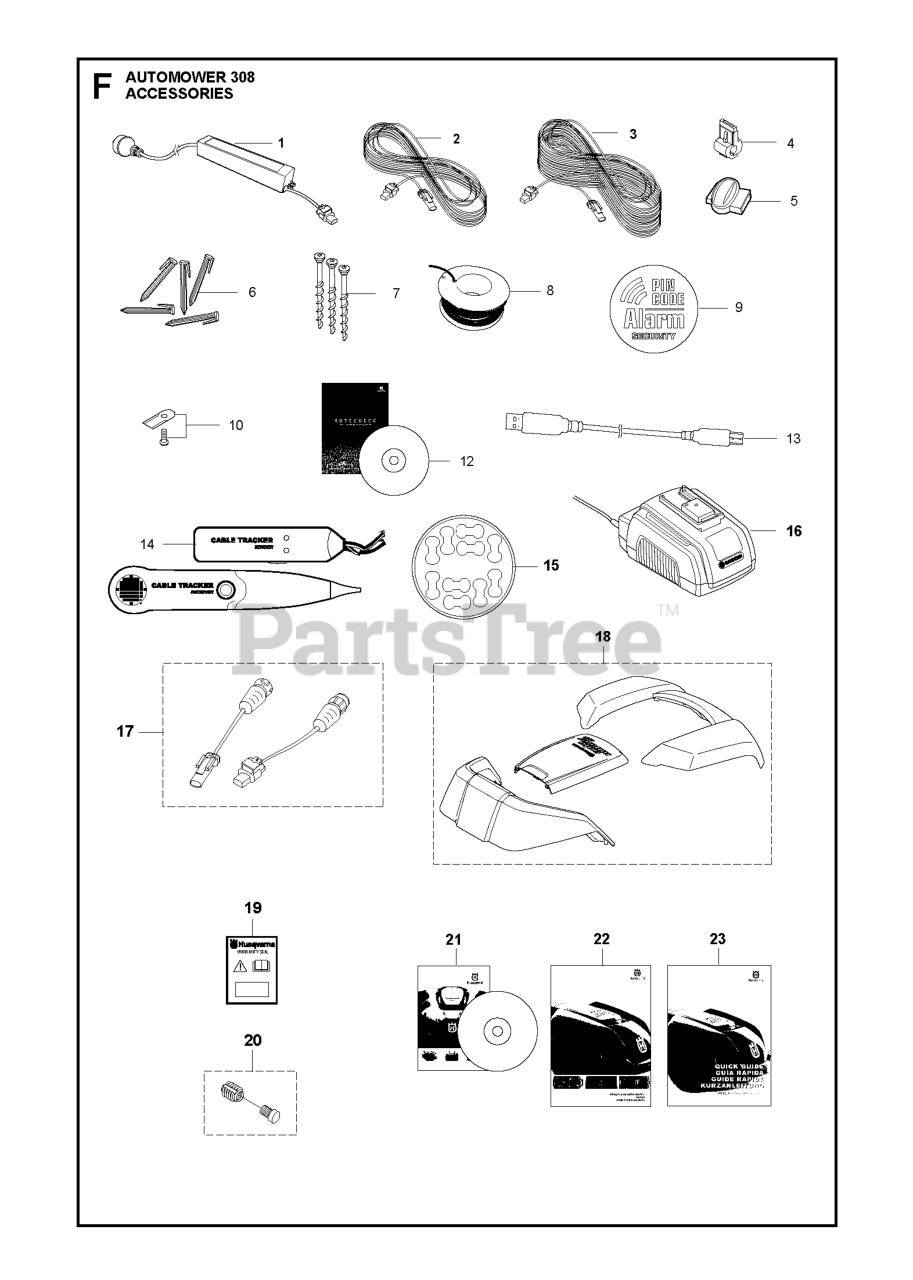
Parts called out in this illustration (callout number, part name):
4	CONNECTOR 5 PCS, BLISTER
4	BRAKER
5	COUPLER SPLICER, 5 PCS,
5	COUPLER SPLICER, 100 PCS
5	SPLICE KIT
6	STAPLE 100 PCS, BLISTER
6	STAPLE 100 PCS
7	SCREW 3 PCS, BLISTER PACK
7	SCREW KIT KIT INCLUDES THREE S
8	WIRE 150M, BLISTER
8	LOOP WIRE 150M
8	WIRE 250M
9	LABEL SECURITY
10	BLADE SET 45 PCS
10	BLADE KIT HUSQVARNA 9 PCS 50HR
10	BLADE SET 300 PCS. CARBON STEE
12	DVD AUTOCHECK EXP SERVICE
13	CABLE WHITE ALT GREY
14	TEST EQUIPMENT
15	STICKER CABLE MARKERS KIT 10PC
19	LABEL WARRANTY SEAL KIT 10 PK
19	LABEL WARRANTY SEAL DEALER
20	THREAD INSERT KIT: THREAD INSE
21	CD DVD MANUALS 305, 308, 310,
